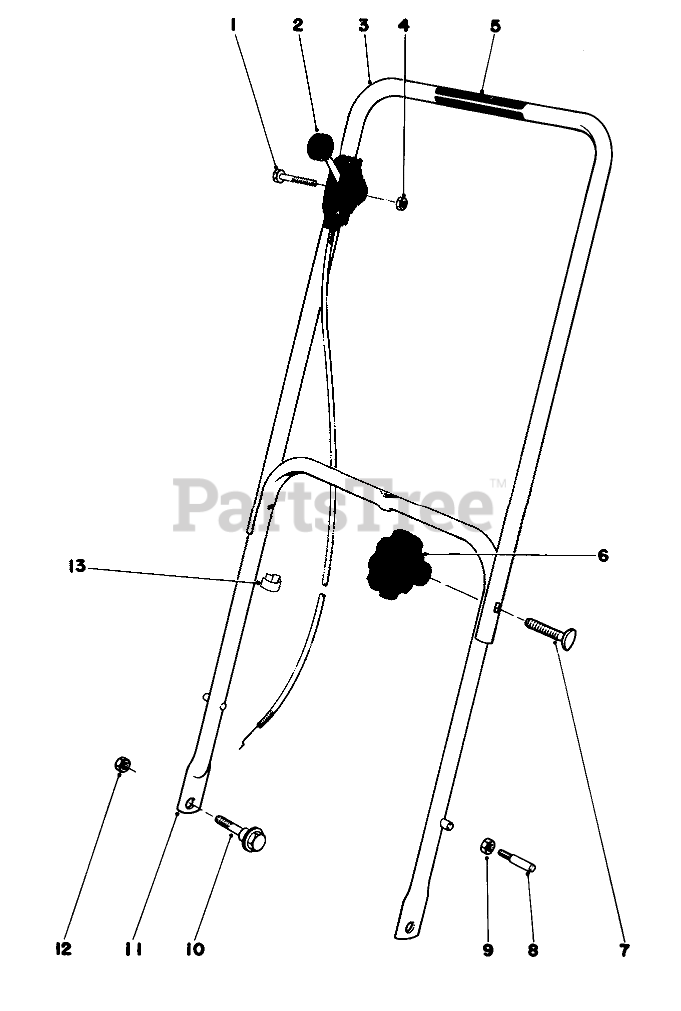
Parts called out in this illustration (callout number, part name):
1	SCREW-HH
2	Throttle Control
3	Upper Handle (Incl . Ref. #5)
4	NUT-LOCK
5	Decal
7	SCREW-HANDLE
8	HANDLE PIN
9	Nut
10	SCREW-SHOULDER
11	LOWER HANDLE ASM SP
12	Nut
